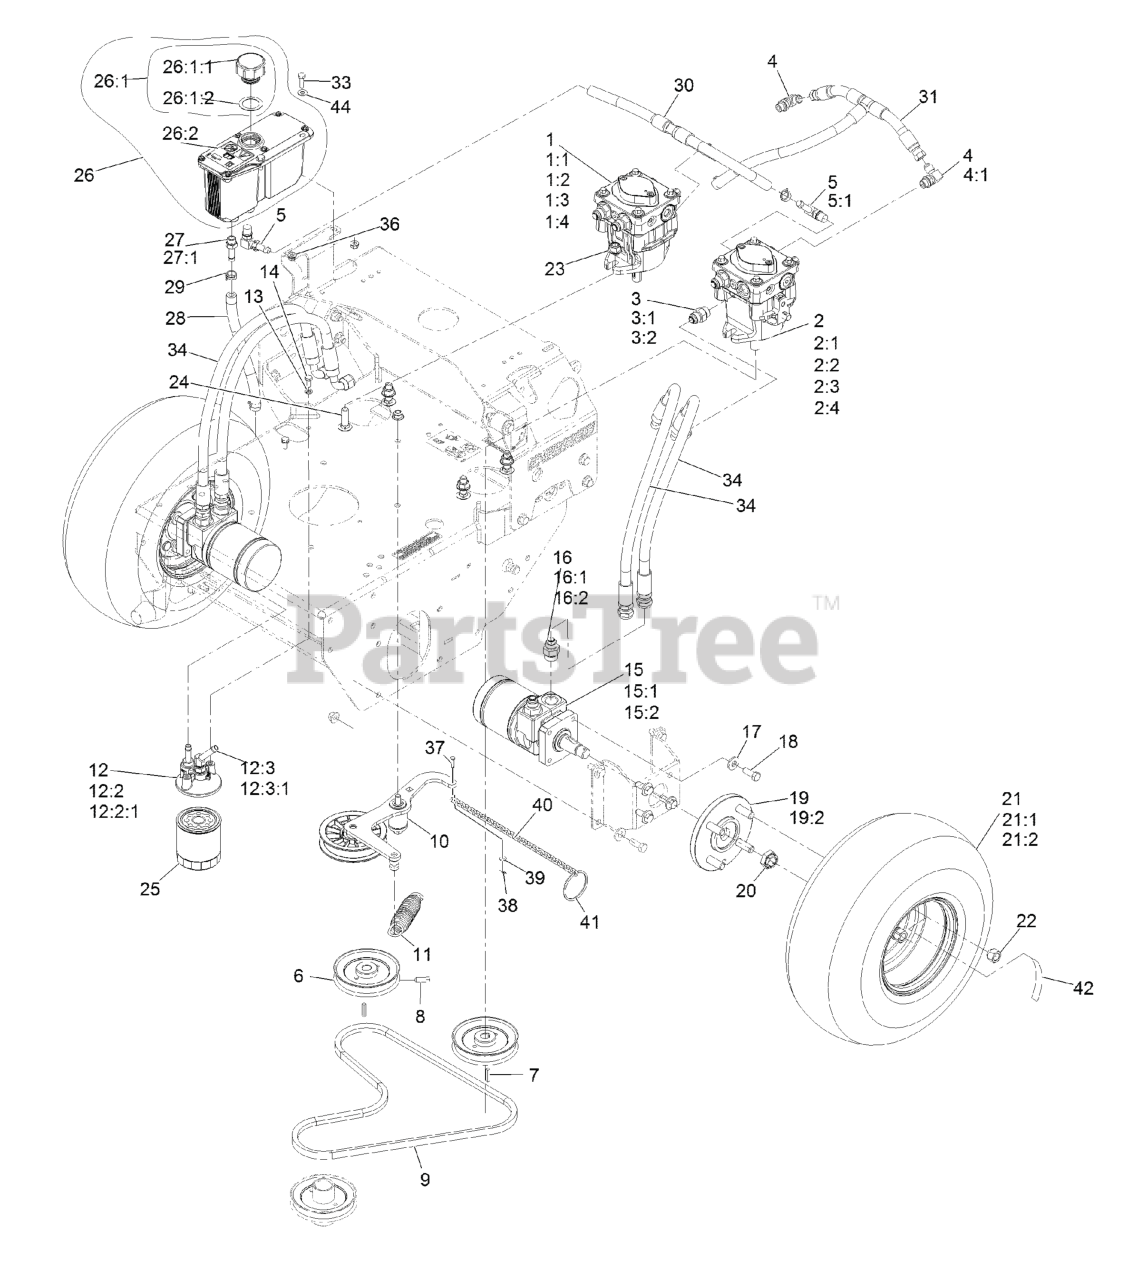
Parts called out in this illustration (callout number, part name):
1	RH HYD PUMP ASM
1:1	INPUT SHAFT KIT
1:2	BEARING-THRUST
1:3	CYLINDER BLOCK KIT
1:4	SEAL OVERHAUL KIT
2	LH HYD PUMP ASM
2:1	INPUT SHAFT KIT
2:2	BEARING-THRUST
2:3	CYLINDER BLOCK KIT
2:4	SEAL OVERHAUL KIT
3	FITTING-STRAIGHT
4	FITTING-ELBOW, 90 DEG
4:1	O-RING
5	FITTING-ELBOW, 90
5:1	O-RING
6	SHEAVE ASM
8	SCREW-SET, SQH
9	BELT
10	ASM, PUMP IDLER
11	SPRING-EXTENSION
12	ASM, FILTER HEAD
12:2	ADAPTER-STRAIGHT
12:2:1	O-RING
12:3	FITTING-BARBED, 45 DEG
12:3:1	O-RING
13	WASHER-LOCK
14	SCREW-HH
15	HYD MOTOR ASM
15:1	SEAL KIT
15:2	BEARING AND SEAL KIT
16	FITTING-STRAIGHT
16:1	O-RING
17	WASHER-BELLEVILLE
18	SCREW-HH
19	WHEEL HUB ASM
19:2	STUD-WHEEL
20	NUT-LOCK
21	WHEEL AND TIRE ASM
21:1	TIRE-TURFMASTER
21:2	RIM-WHEEL
22	NUT-LUG
23	NUT-HF, NI
24	BOLT-CARR
25	FILTER-25 MICRON, BI-DIRE
26:1	Reservoir-HYD
26:1:1	Cap-Reservoir, HYD
26:1:2	GASKET-CAP
26:2	DECAL-WARNING
27	ADAPTER-STRAIGHT
27:1	O-RING
28	HOSE-CHARGE
29	CLAMP-HOSE
30	HOSE-CASE DRAIN
31	HOSE-CHARGE
33	SCREW-HWH
34	HYD HOSE ASM
37	PIN-CLEVIS
38	PIN-HAIR
39	WASHER-PLAIN
40	CHAIN-LINK, TWIST
41	RING-SPLIT
42	DECAL-TORQUE WHEEL LUG-HU
